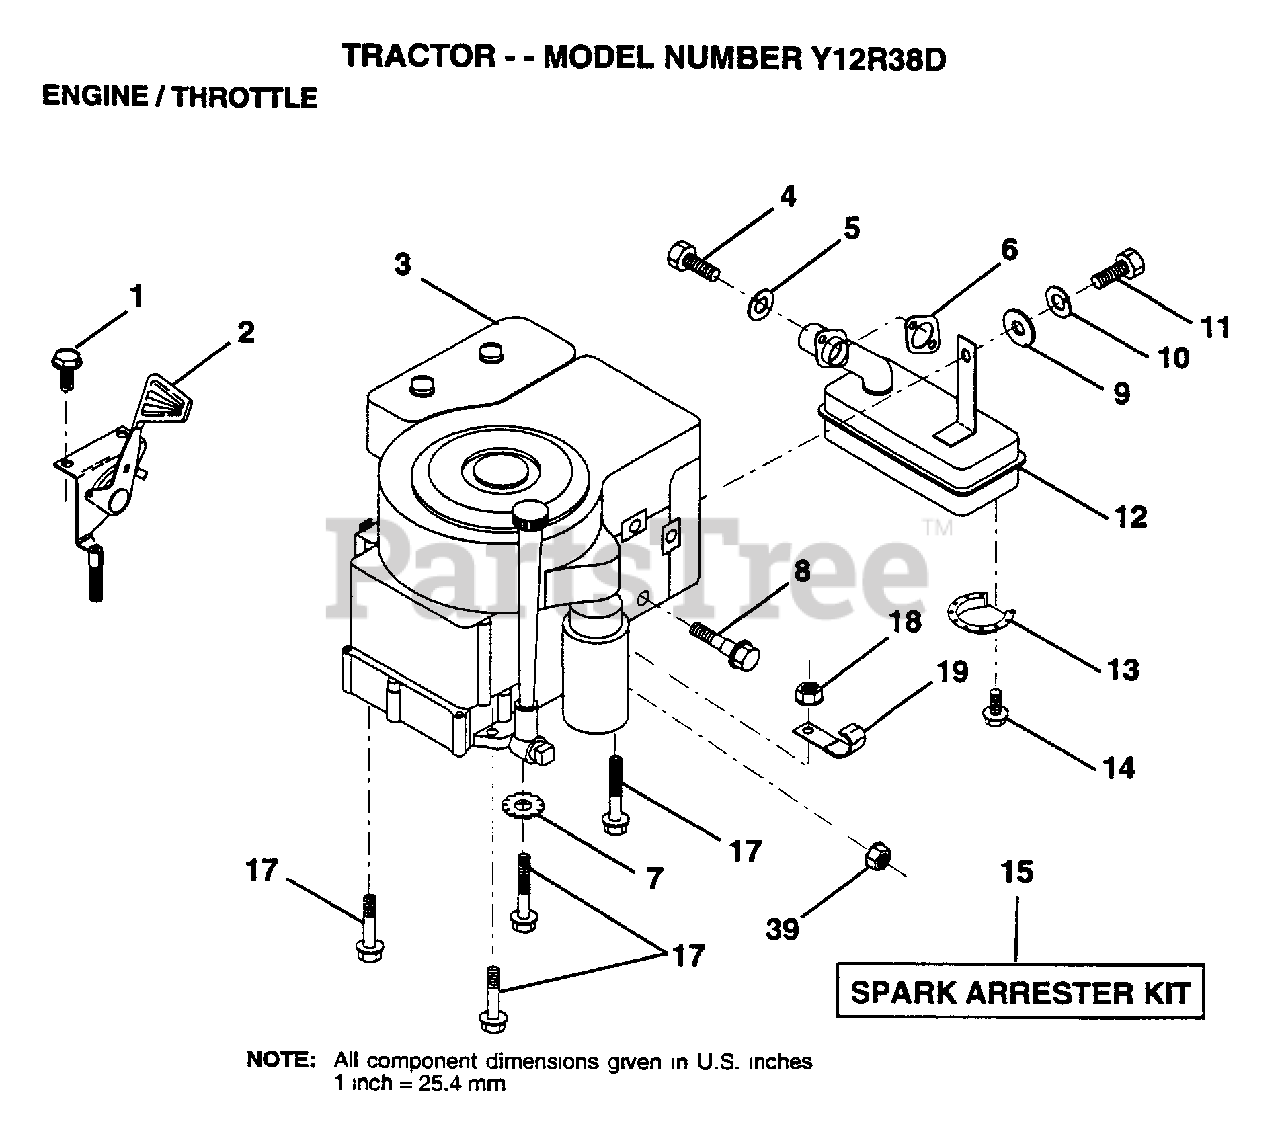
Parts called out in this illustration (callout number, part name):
1	SCREW.1/4-20X1/2
2	"CONTROL,THROTTLE"
4	SCREW
5	LOCKWASHER
7	LOCKWASHER
8	BOLT T
10	LOCKWASHER
12	MUFFLER
13	DEFLECTOR.222573
17	SCREW LT
18	NUT
19	CLIP T
39	NUT
